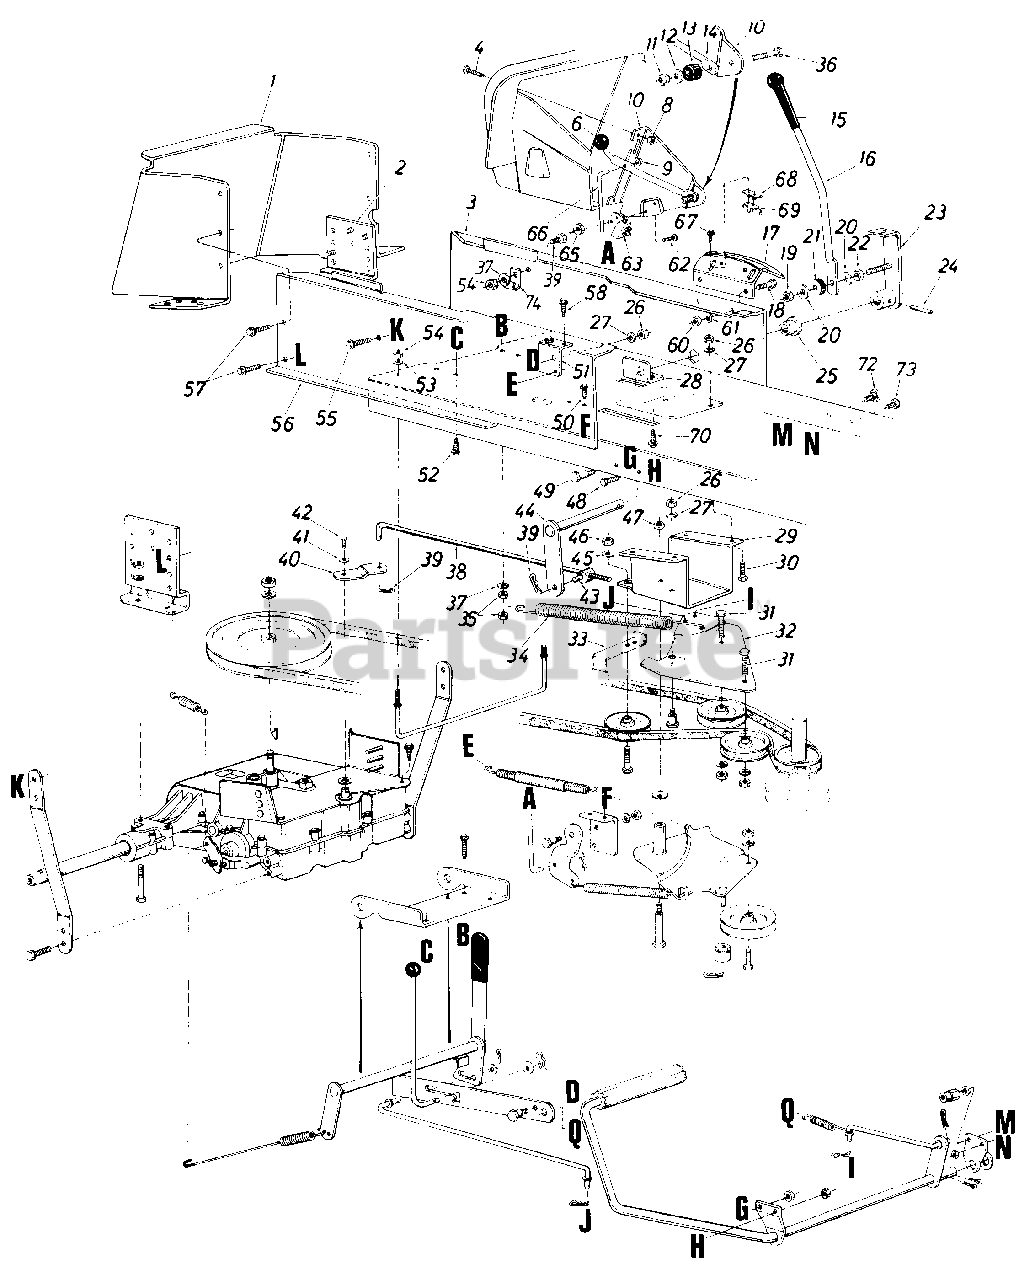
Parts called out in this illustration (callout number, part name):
1	Hitch Plate
2	Transaxle Support Bracket
3	Side Panel Upper Frame L.H.
4	Truss. Mach. Scr. 1/4-20 x .50" Lg.*
6	Ball Knob
8	Hex Sems Nut 1/4-20 Thd*
9	Push Cap 1/4" Rod
10	Deck Clutch Control Brkt.
11	Hex Cent L-Nut 1/4-20 Thd.
12	Fl-Wash. .281" I.D. x .734" O.D. x .063 Thk.
13	Rubber Wash. .330" I.D. x .87" O.D. x .32 Thk.
14	Blade Clutch Lever
16	Shift Lever
19	Hex Cent. L-Nut 5/16-18 Thd.
20	Fl-Wash. .344" I.D. x .875" O.D. x .063 Thk.
21	Rubber Wash. .330" I.D. x .87" O.D. x .32 Thk.
22	Hex Nut 5/16-18 Thd.*
23	Handle Mount Brkt. Ass'y.
24	Spring F'in Spiral 1/4" Dia. x 1.5" Lg.
25	Plastic Hex Bearing .625" I.D.
26	Hex Nut 5/16-18 Thd.*
27	L-Wash. 5/16" I.D.*
28	Speed Control Shaft Brkt.
29	Transaxle Clutch Support Brkt.
30	Hex Bolt 5/16-18 x 1.0" Lg.
31	Hex Bolt 3/8-24 x 1.5" Lg.
32	Idler Bracket Ass'y.
35	Hex Cent. L-Nut 1/4-20 Thd.
36	Hex Bolt 1/4-20 x .625" Lg.*
37	L-Wash. 1/4" I.D.*
38	Shift Link
39	Hairpin Cotter 3/8"
40	Shifter Bracket
41	Belleville Wash. .25" 1. ,) . x.375" O.D.
42	Hex Bolt 1/4-28 x .62" Lg.
43	Pivot Bushing
44	Speed Control Shaft Ass'y.
45	Fl-Wash. .385" I.D. x .87" O.D. x .060 Thk.
46	Hex Cent. L-Nut 3/8-24 Thd.
47	Hex Cent. L-Nut 3/8-16 Thd.
48	Hex Bolt 3/8-16 x .62" Lg.*
49	Shoulder Bolt .500" Dia. x .340" Lg. (3/8-16)
50	Hex Thd. Rolling Scr. 1/4-20 x.50" Lg.
51	Parking Brake Cam Mtg. Brkt.
52	Hex Thd. Rolling Scr. 1/4-20 x.50" Lg.
53	L-Wash. 1/4" I.D.*
54	Hex Nut 1/4-20 Thd.*
55	Hex Wash. Hd. TT-Tap Scr. 3/8-16 x .5" Lg.
56	Side Panel Upper Frame-R. H .
57	Hex Thd. Rolling Scr. 5/16-24 x .50" Lg.
58	Hex Thd. Rolling Scr. 1/4-20 x.50" Lg.
60	Hex Nut 5/16-18 Thd.*
61	L-Wash. 5/16" I.D.*
62	Truss Mach. Scr. #10-24 x .50" Lg.*
63	Safety Switch
65	Hex Nut #10-24 Thd.*
66	Deck Control Rod
67	Hex Wash. Hd. Scr. #8 x .50" Lg.
68	Insulator Nut Plate
69	Spring Switch
70	Hex Wash. Hd. AB-Tap Scr. 5/16 x .75" Lg.
72	Shld. Bolt .498" Dia. x .34"
73	Hex Bolt 3/8-16 x .62" Lg.
74	Clamp
